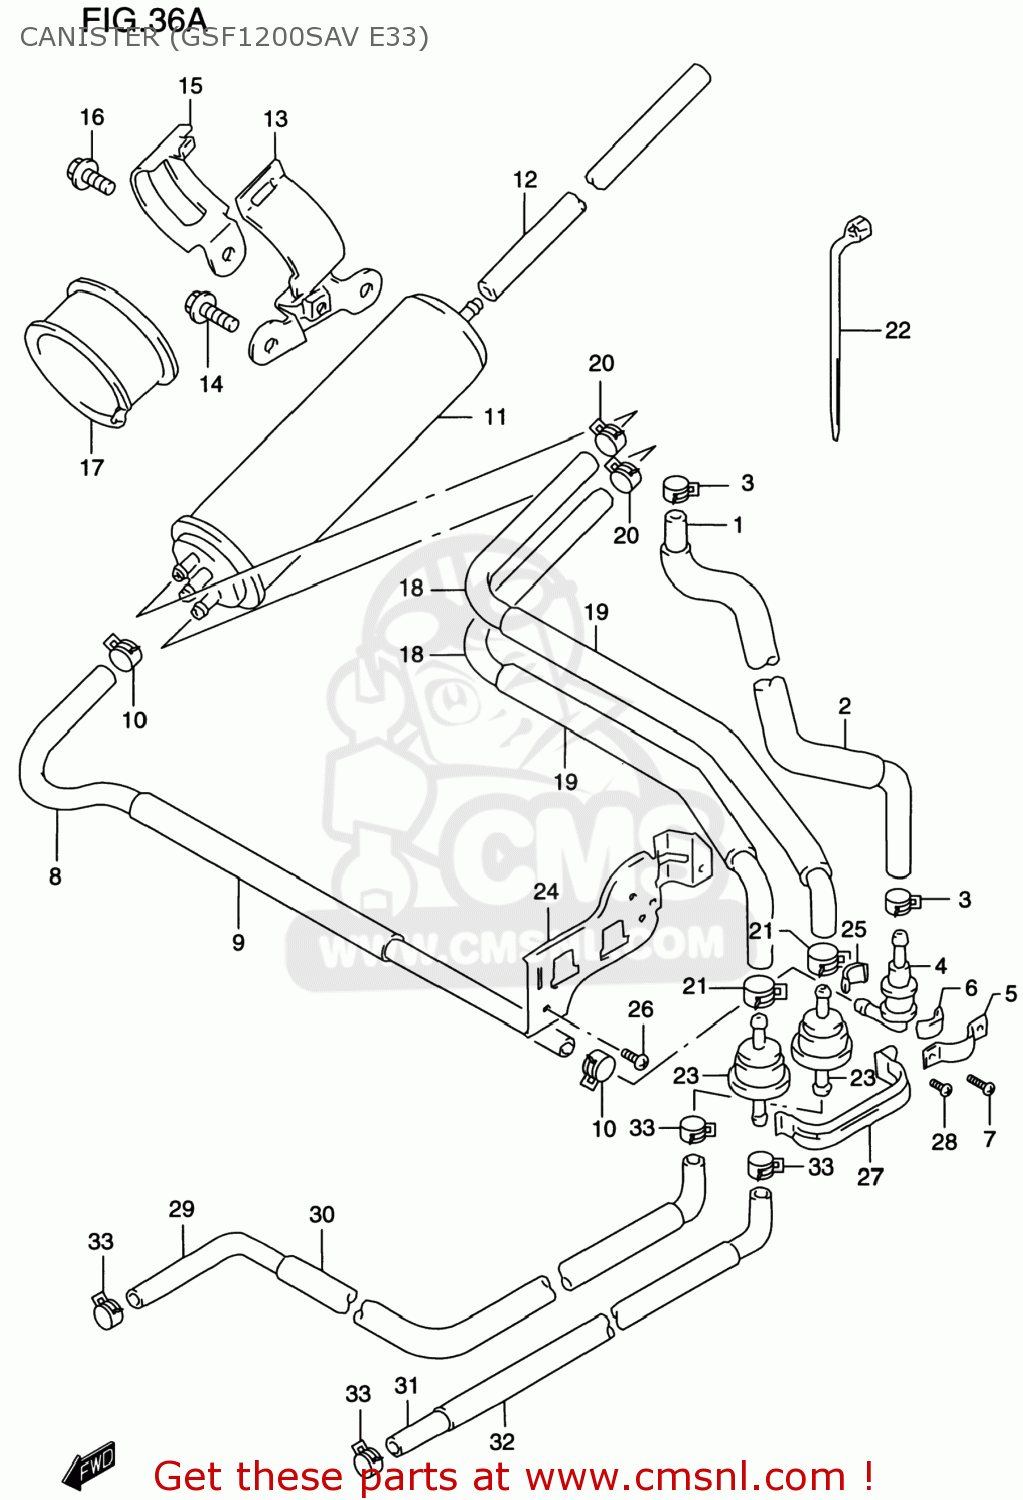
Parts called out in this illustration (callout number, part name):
1	HOSE,TANK & BREATHER VALVE
2	PROTECTOR(14.5X15.5X600)
3	CLIP
4	VALVE,FUEL TANK BREATHER
5	PLATE,FUEL TANK BREATHER NO.2
6	CUSHION
7	SCREW
8	HOSE,CANISTER & BREATHER VALVE
9	PROTECTOR(14.5X15.5X600)
10	CLIP
11	CANISTER ASSY,CHARCOAL
12	HOSE(7X12X600)
13	BRACKET,CANISTER
14	BOLT
15	HOLDER,CANISTER
16	SCREW 6X12
17	CUSHION,CANISTER
18	HOSE,CANISTER & PURGE VALVE
19	PROTECTOR(14.5X15.5X600)
20	CLIP
21	CLIP
22	CLAMP(L:125)
23	VALVE,CANISTER PURGE
24	PLATE COMP,BREATHER VALVE
25	CUSHION
26	SCREW 6X12
27	HOLDER,CANISTER PURGE
28	SCREW
29	HOSE,CARBURETOR & PURGE VALVE
30	PROTECTOR(14.5X15.5X600)
31	HOSE,CARBURETOR & PURGE VALVE
32	PROTECTOR(14.5X15.5X600)
33	CLIP
